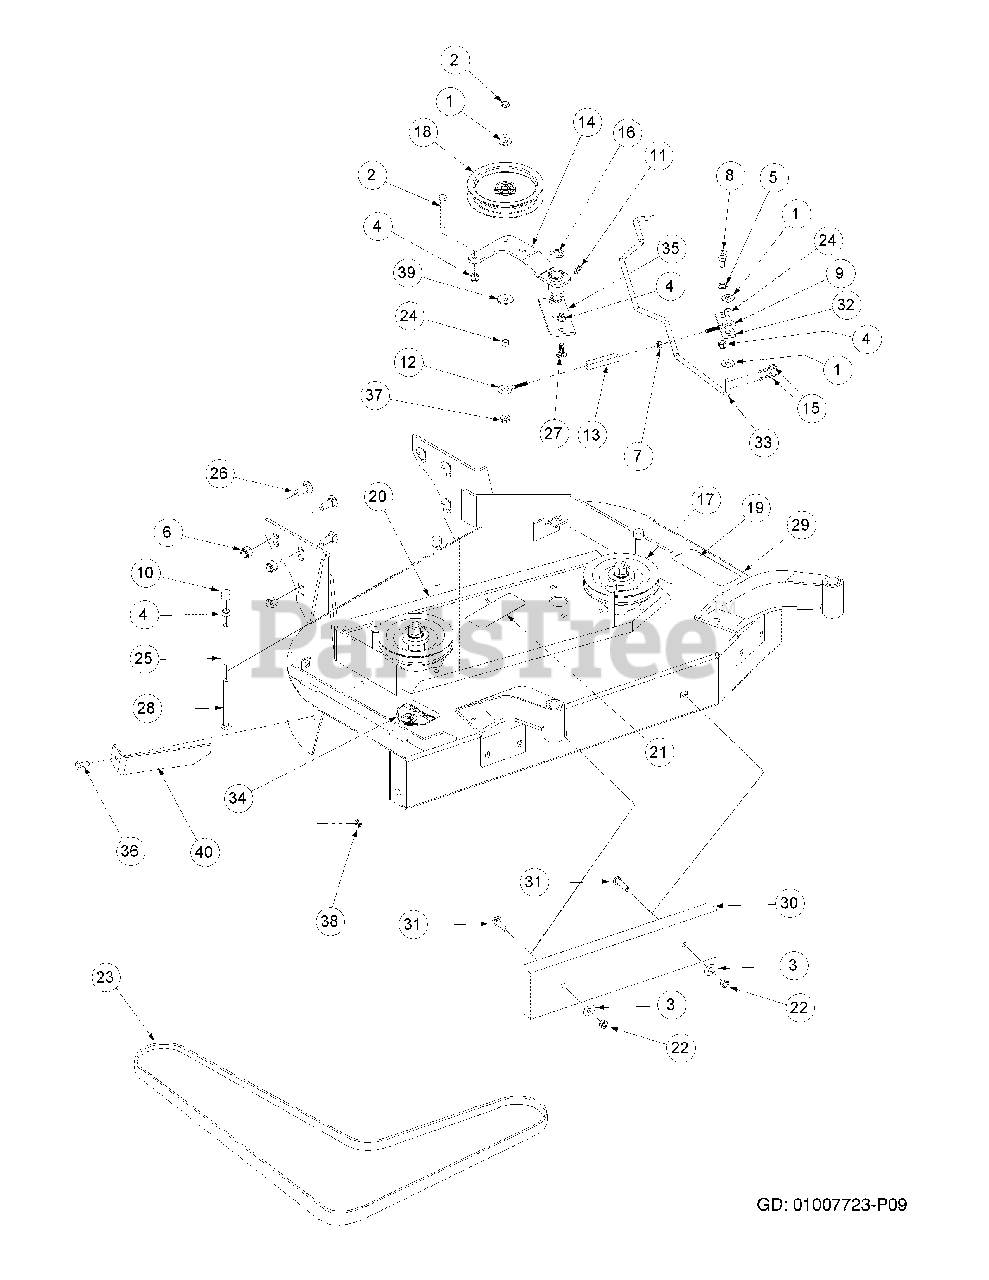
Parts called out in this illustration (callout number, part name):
1	Flat Washer, 3/8 Zinc
2	Hex Cap Screw, 3/8-16 x 2.75
3	Flat Washer, 3/8 Zinc
4	Lock Nut, Nylon Insert, 3/8-16
5	Shim Washer
6	Nut, Flange Lock, 1/2-13
7	Hex Nut, 5/16-18
8	Shoulder Bolt
9	Eye Bolt, Right Hand
10	Cap, Black Vinyl
11	Grease Fitting, 45°, 1/4-28
12	Eye Bolt, Left Hand
13	Turnbuckle
14	Idler Arm
15	Hair Pin, 3/8"-1/2"
16	E-Ring, Retainer
17	Pulley Deck
18	Idler Deck Take-up
19	Decal Rotating Blade
20	Deck Stiffener
21	Decal, Warning Shield Missing
22	Lock Nut, 3/8-16
23	Belt Drive
24	Turnbuckle, Sleeve
25	Spacer, Belt Guide
26	Carriage Bolt, 1/2-13 x 1-1/4
27	Carriage Bolt, 3/8-16 x 1
28	Carriage Bolt, 3/8-16 x 4.5
31	Carriage Bolt, 3/8-16 x 1-1/2
33	Rod Clutch Link
34	Decal, Danger Hands and Feet
35	Idler Base
36	Hex Cap Screw, 5/16-18 x .75
37	Hex Nut Flange Lock, 3/8-16
38	Nut, Hex Flange Lock, 5/16-18
39	Washer, 1.25 x .411 x .100
